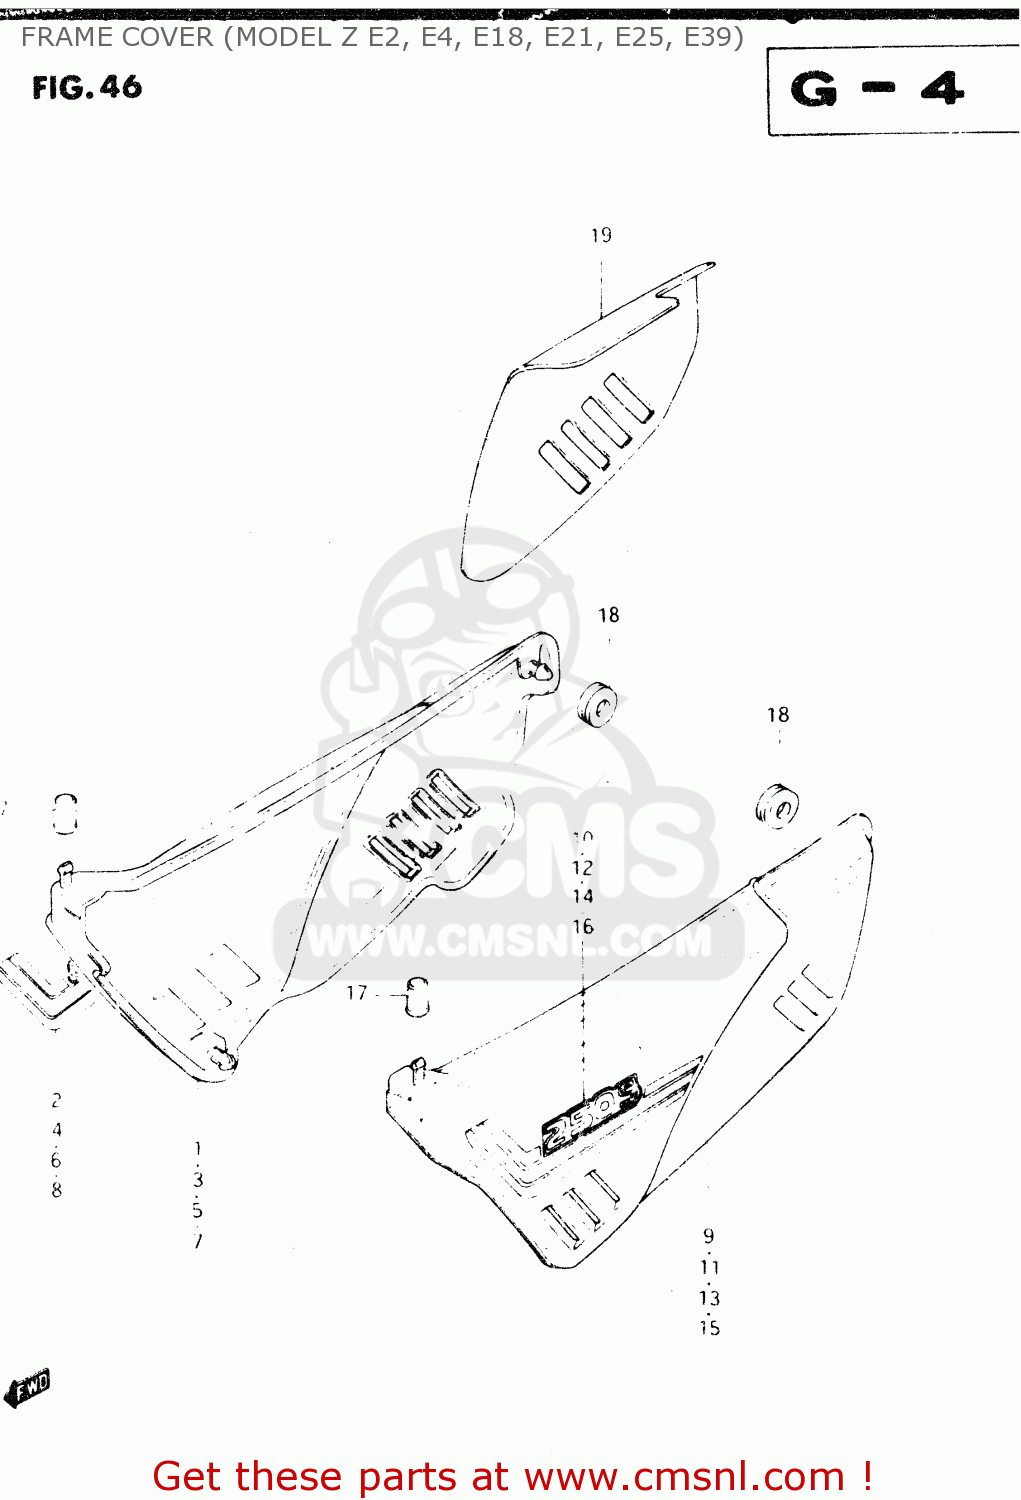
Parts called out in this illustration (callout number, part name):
1	COVER, FRAME RH (BLACK)
2	TAPE, RH
3	COVER, FRAME RH (BLUE)
4	TAPE, RH
5	COVER, FRAME RH (YELLOW)
6	TAPE, RH
7	COVER,FRAME,RIGHT
8	TAPE, RH
9	COVER, FRAME LH (BLACK)
10	TAPE, LH
11	COVER, FRAME LH (BLUE)
12	TAPE, LH
13	COVER, FRAME LH (YELLOW)
14	TAPE, LH
15	COVER, FRAME LH (RED)
16	TAPE, LH
17	CUSHION
18	CUSHION
19	HEAT SHIELD,FRAME COVER
